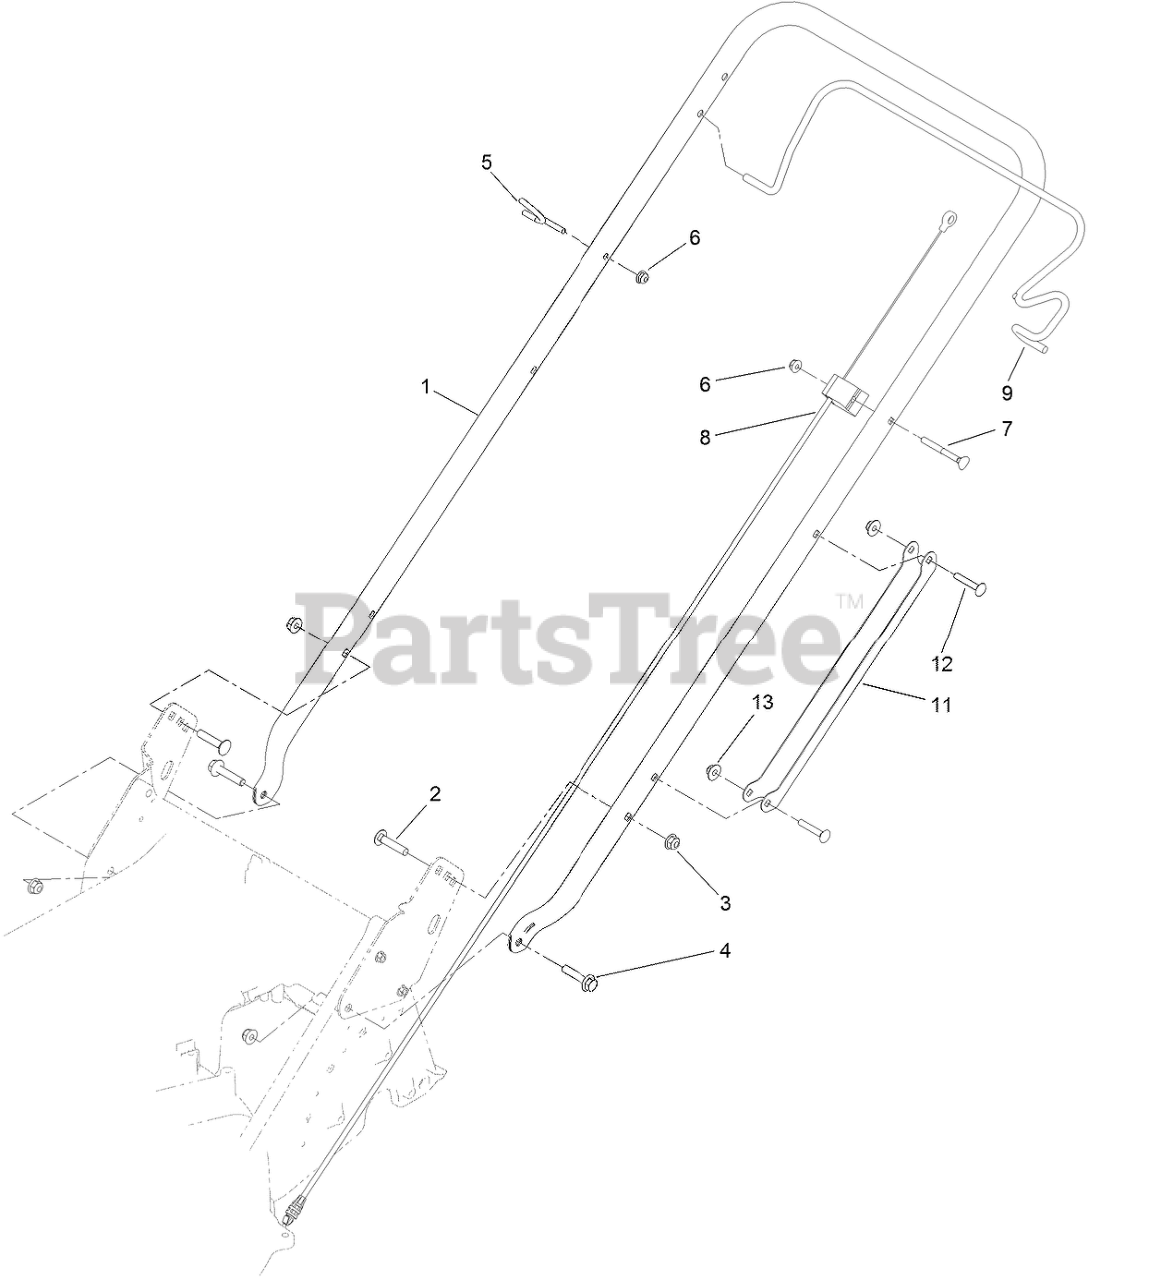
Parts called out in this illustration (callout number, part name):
1	HANDLE
2	BOLT-CARR
3	NUT-HF, NI
4	SCREW-HHF
5	GUIDE-ROPE
6	NUT-HF
7	SCREW-HANDLE
8	CABLE-BRAKE
9	BAIL-BRAKE
11	GUARD-CABLE, HANDLE
12	SCREW-CARR
13	NUT-HEX FLG
